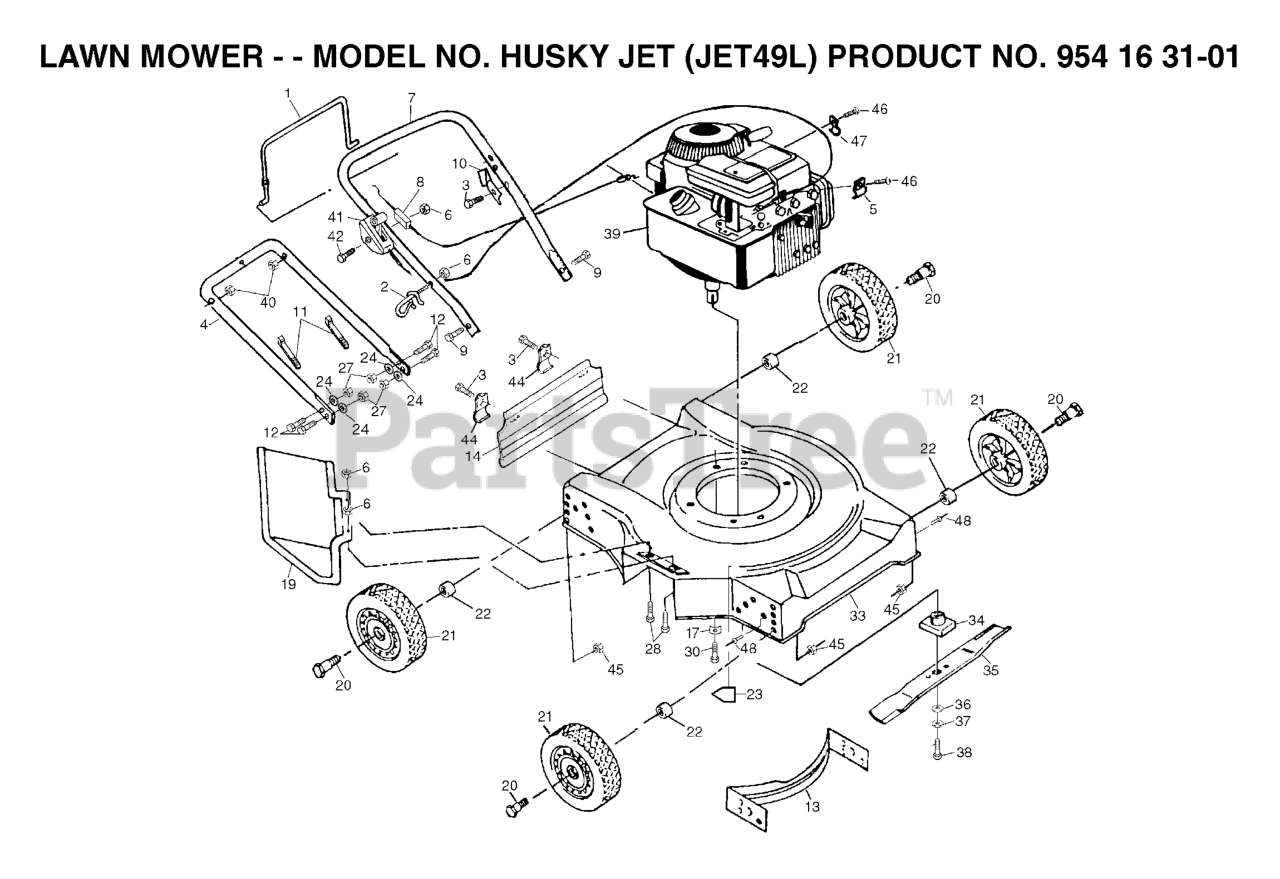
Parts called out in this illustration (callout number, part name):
1	CONTROL BAR
2	ROPE, GUIDE
3	TAPPING SCREW
5	WASHER
6	NUT
8	CABLE.CONTROL.MZR.RH.SP/PUSH
9	BOLT
10	BRACKET UPSTOP
11	TIE GUIDE
13	BAFFLE
14	REAR SKIRT
17	WASHER.ENGINE.BZP
21	WHEEL
22	SPACER.WHEEL.390.X1.0X.380.RTA
23	DECAL MOWER CUT/FINGER
27	FLANGED LOCKNUT 3/8-16 ZINC
28	BOLT.HEX.1/4.X.3/4.DICHROMATE
30	BOLT 3/8-16X1-1/8
34	BLADE ADAPTOR
35	20" Blade
36	WASHER,HARDEN
37	LOCKWASHER
38	SCREW, HEX HD 3/8-24 X 1-3/8
40	NUT
41	THROTTLE CONTROL
42	SCREW.PAN.HEAD
44	BRACKET DEFL PM
45	LOCKNUT PM
46	SCREW.HEX.HEAD.WASHER.10-16
47	GUIDE CLIP PM
